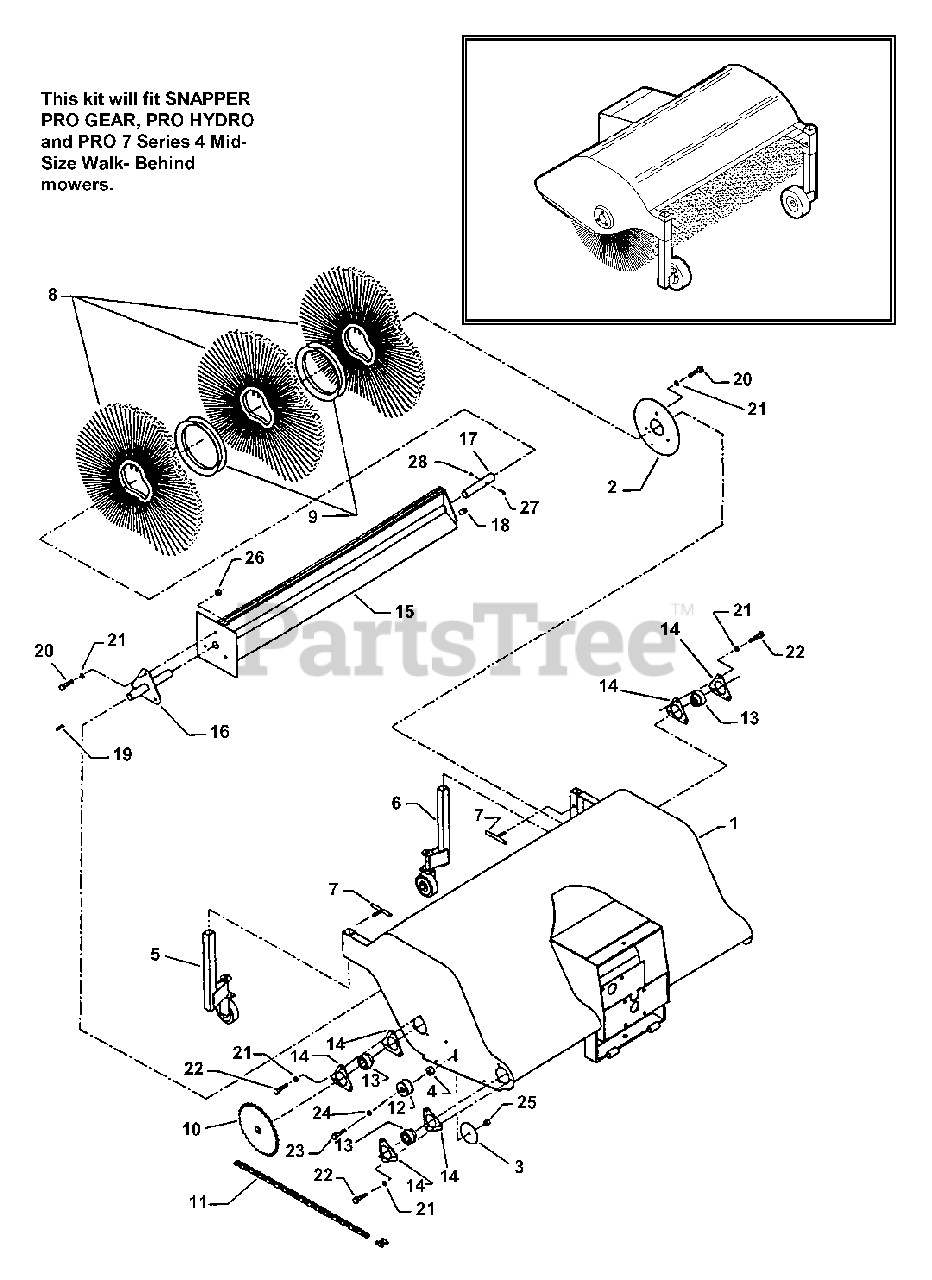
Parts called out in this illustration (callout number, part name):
1	HOUSING
2	DISC, Brush Retaining
3	WASHER, Chain Idler
4	SPACER, Chain Idler
5	ASSEMBLY, Left Gauge Wheel
6	ASSEMBLY, Right Gauge Wheel
7	SCREW, Locking
8	BRUSH, Zigzag
9	RING, Spacer
10	SPROCKET, Driven (401348)
11	CHAIN #40 w/Connecting Link
12	IDLER, Chain
13	BEARING w/Locking Collar
14	BEARING FLANGE (3 holes)
15	SUPPORT, Brush
16	DRIVE SHAFT
17	DRIVEN SHAFT
18	ANCHOR NUT, 5/16-18
19	KEY, 1/4" Square x 1-1/4"
20	BOLT, 5/16-18 x 1" Hex
21	WASHER, 5/16" Lock
22	BOLT, 5/16-18 x 3/4" Hex
23	BOLT, 3/8-16 x 2" Hex
24	WASHER, 3/8" Lock
25	NUT, 3/8-16 Hex
26	NUT, 5/16-18 Hex
27	BOLT, 1/4-20 x 1-1/2" Hex
28	NUT, 1/4-20 Stover
